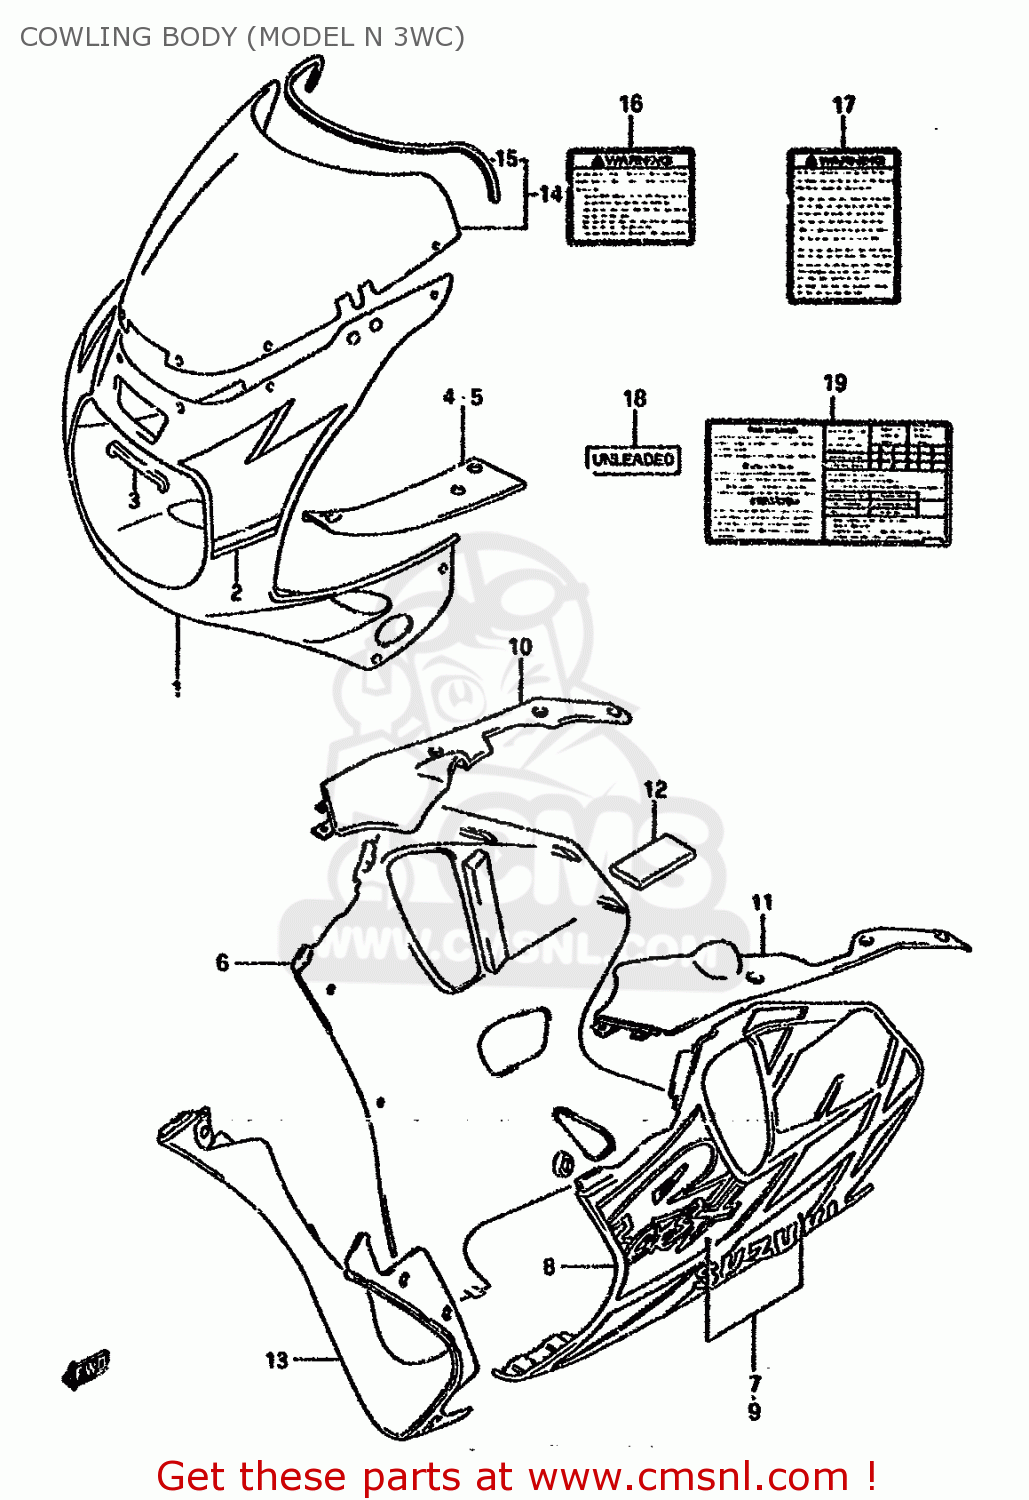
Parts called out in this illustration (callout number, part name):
1	COWLING ASSY,BODY
2	TAPE SET,UPPER
3	CUSHION,FR POSITION LAMP
4	PANEL,UPR,R
5	PANEL,UPR,L
6	COWLING ASSY,UNDER RH (BLACK)
7	TAPE SET,COWL UNDER,R
8	COWLING ASSY,UNDER,L
9	TAPE SET,COWL UNDER,L
10	PANEL,LWR,R
11	PANEL,LWR,L
12	CUSHION,PANEL
13	COWLING,UNDER CTR
14	WINDSCREEN SET
15	MOLDING
16	LABEL, WARNING SAFETY
17	LABEL (WARNING SCREEN)
18	LABEL,CAUTION
19	LABEL,TIRE AIR PRESSURE
